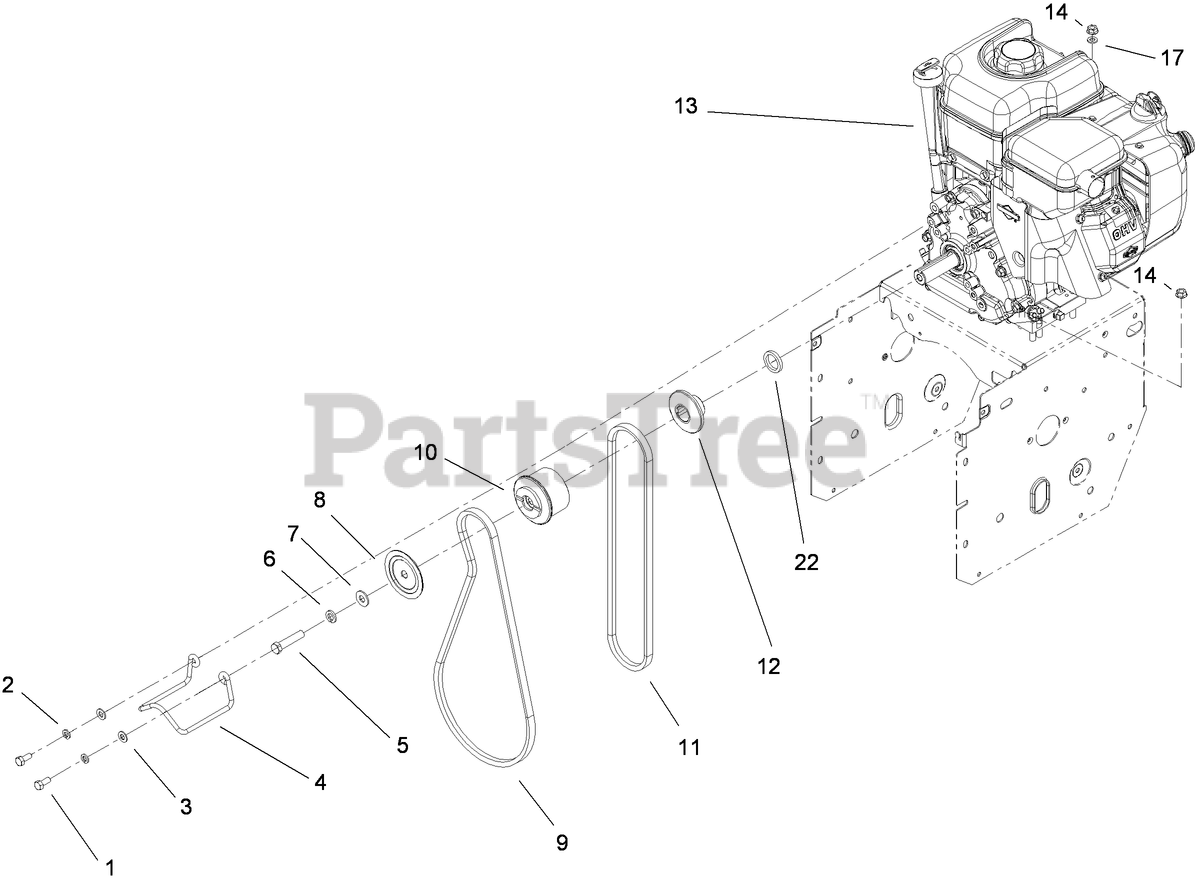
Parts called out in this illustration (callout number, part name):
1	SCREW-HH
2	WASHER-LOCK
3	WASHER-PLAIN
5	SCREW-HH
6	WASHER-LOCK
7	WASHER-FLAT
8	SHEAVE-HALF, IMPELLER
9	BELT-V
10	PULLEY-ENGINE, CENTER
11	V BELT-TRACTION
12	SHEAVE-HALF, TRACTION
14	NUT-HF
17	WASHER-FLAT
22	SPACER-HARDENED
